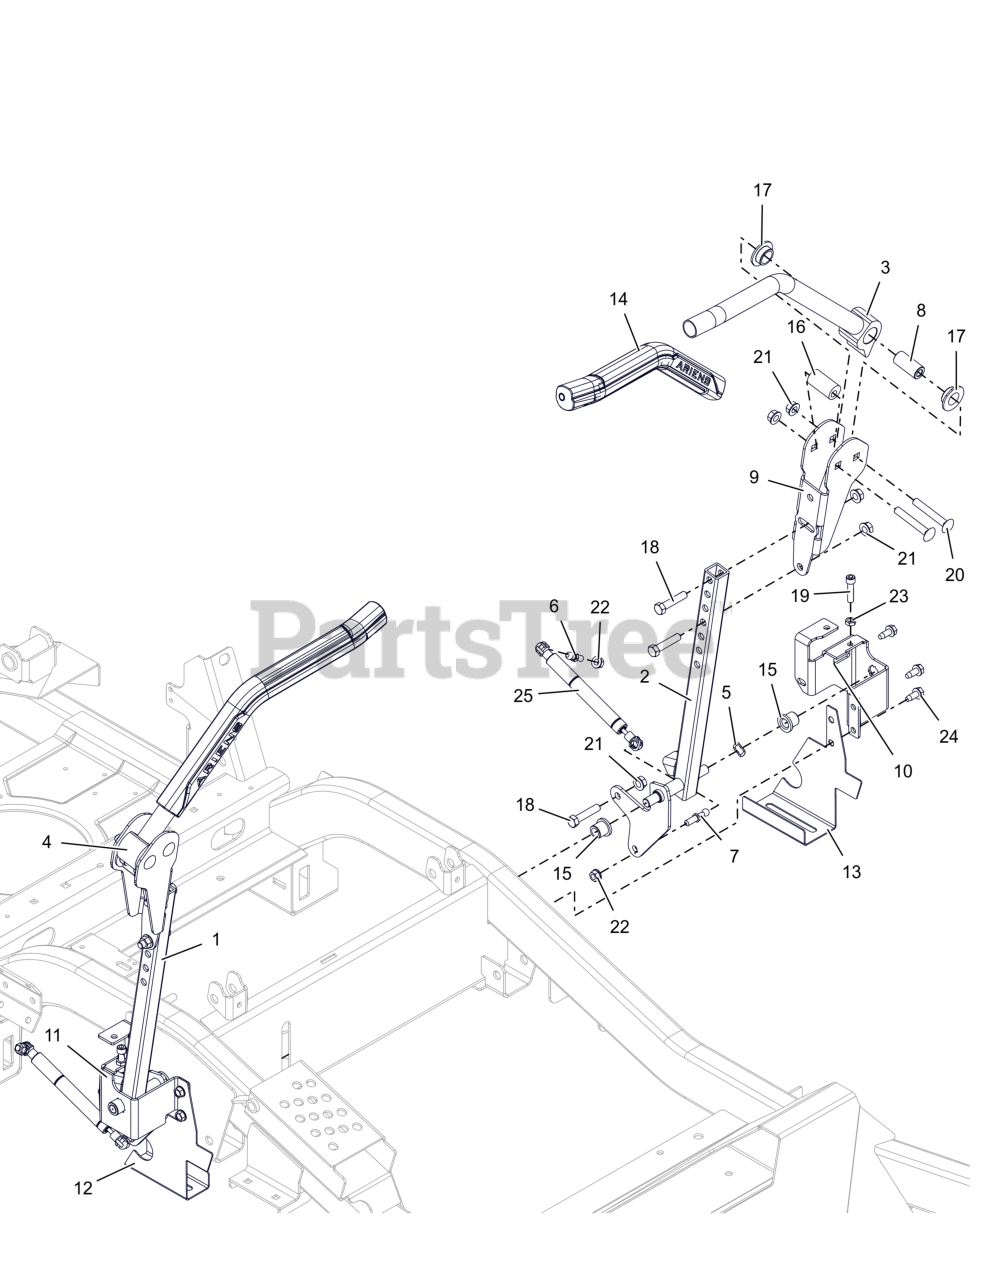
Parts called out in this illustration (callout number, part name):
1	WLDMT, STEERING RH
2	WLDMT, STEERING LH
3	WLDMT, CONTROL HANDLE-LH (BLACK)
4	WLDMT, CONTROL HANDLE-RH (BLACK)
5	WAVE WASHER .531X.781X.125FH
6	STUD- BALL
7	STUD-BALL-THREADED
8	SPACER, STEERING ARM
9	ADJ UPPER CONTROL ARM BRKT-BLK
10	BRKT, STEERING ARM MOUNT -LH
11	BRKT, STEERING ARM MOUNT -RH
12	GUARD, FRAME RAIL BELT RH
13	GUARD, FRAME RAIL BELT LH
14	GRIP- HANDLEBAR ARIENS
15	BHSG-FLG .500X.750X.750X.125
16	BSHG, ECCENTRIC.406X.875X1.625
17	BSHG-FLG .762X1.48X.44 IGLIDER
18	BLT, HEX .38-16X1.75 G5 ZCC
19	BLT, SHCS .312-18X1.25 G8 SS
20	BLT, RHSSN.38-16X2.50 G5 ZCC
21	NUT-LK-TOP-FLG .38-16 ZC120
22	NUT,LK-CTR-FLG .31-18 GF ZCC
23	NUT-JAM .312-18 G2 ZCC
24	SCR,TAP .312-18X.75 HWH TR ZCC
